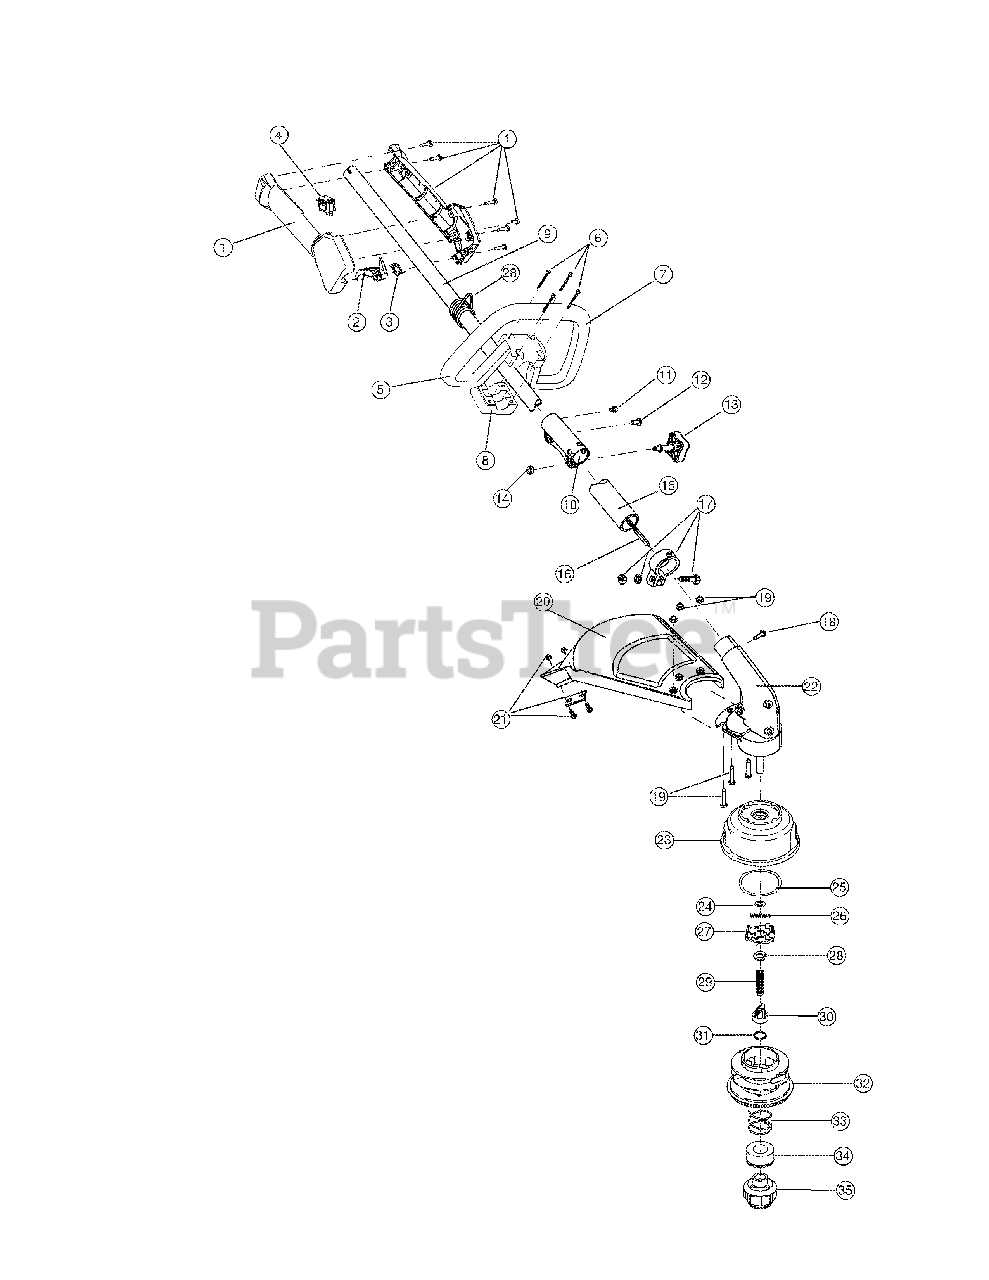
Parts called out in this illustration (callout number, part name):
1	Throttle Housing Assembly (includes 2 & 3)
2	Throttle Trigger
3	Throttle Trigger Spring
4	Switch Assembly
5	Deluxe D-Handle Assembly ( includes 6-8)
6	Handle Mount Hardware
7	Deluxe D-Handle
8	Bottom Clamp
9	Upper Drive Shaft Housing Assembly
10	Split Boom Coupler (includes 11-14)
13	Adjustment Knob
14	Knob Retaining Nut
15	Lower Drive Shaft Housing Assembly
16	Lower Flexible Drive Shaft
17	Lower Clamp Assembly (includes 18)
18	Anti-Rotation Screw
19	Shield Mounting Hardware
20	Shield and Blade Assembly (includes 21)
21	Blade Assembly
22	Gearbox Assembly
23	Outer Spool Assembly (includes 24)
24	Retaining Ring
25	Thrust Washer
26	Small Spring
32	Inner Reel
33	Large Spring
35	Bump Head Knob Assembly (includes 33 & 34)
